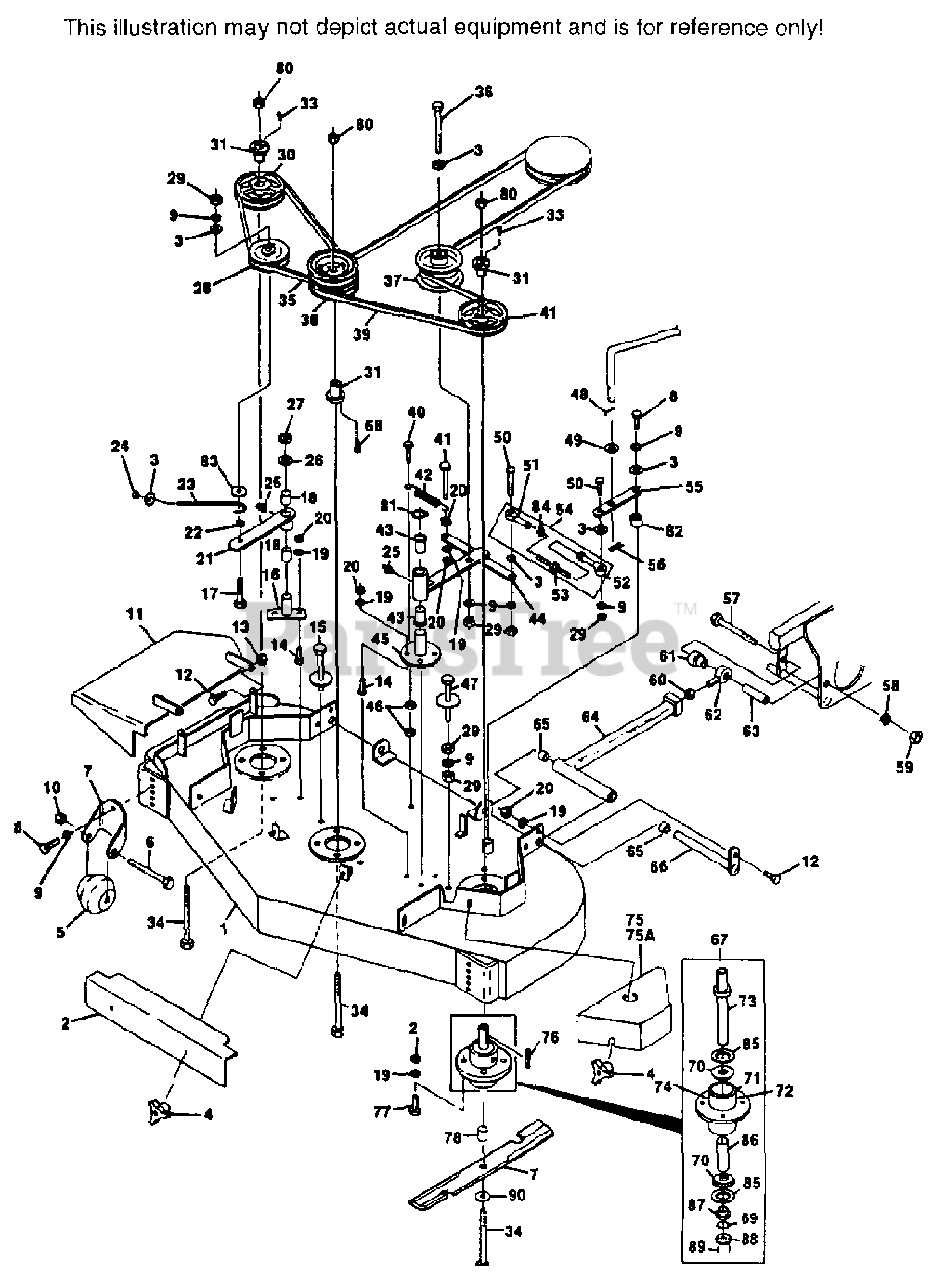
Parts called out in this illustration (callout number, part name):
1	CUTTER DECK(INCLUDES DECALS)
2	BELT COVER - FRONT
4	WING NUT, 3/8-16
5	ANTI-SCALP WHEEL
7	ANTI-SCALP WHEEL BRACKET
10	HEX NUT, 5/8-11 ELASTIC STOP
11	DISCHARGE CHUTE
13	HEX NUT, 5/16-18 ELASTIC STOP
15	BELT GUIDE
18	BUSHING
21	IDLER ARM(INCLUDES BUSHINGS & GREASE FTG.)
22	SPACER
23	"J" ROD
24	HEX NUT, 3/8-16 ELASTIC STOP
25	GREASE FITTING
26	FLAT WASHER, 3/4" SPECIAL
27	RETAINING RING, 3/4" EXTERNAL "E"
28	PULLEY, IDLER
30	PULLEY(INCLUDES ITEMS 31 & 33)
31	TAPERED HUB
34	HEX HEAD BOLT, 5/8-11 X 9-1/2"
35	BELT, RH BLADE DRIVE
37	PULLEY, IDLER - CUTTER ENGAGEMENT
38	PULLEY, DOUBLE(INCLUDES 31)
39	BELT, BLADE DRIVE
41	PULLEY, LH SPINDLE
43	BUSHING
44	IDLER ARM(INCLUDES BUSHINGS & GREASE
45	IDLER PIVOT BASE
47	BELT GUIDE
51	BALL JOINT - RH
52	BALL JOINT - LH
54	TURNBUCKLE ASSEMBLY
55	DECLUTCH LINK, CUTTER ENGAGEMENT
56	HAIR PIN, 1/8" DIA.
60	HEX NUT, 5/8-18 UNF
62	ROD END
63	SPACER
64	PUSH ARM(INCLUDES 25, 60, 62, & 65)
65	BUSHING
66	PUSH ARM SHAFT
67	CUTTER SPINDLE ASSY(COMPLETE, TAPERED)
69	RETAINING RING, 1" EXT INVERTED
70	BEARING & CUP, TAPERED SPINDLE
71	SPINDLE HOUSING, TAPERED SPINDLE
72	GREASE FITTING
73	SPINDLE SHAFT, TAPERED SPINDLE
74	RELIEF FITTING, TAPERED SPINDLE
75	BELT COVER - RH
75A	BELT COVER - LH
76	KEY, 1/4 X 1/4 X 2"
78	SPACER-USE WITH TAPER BEARING SPINDLE
81	RETAINING RING 1-1/8" EXT. E
83	3/8 FLATWASHER, 3/8 X 1-1/2 X .06
84	HEX NUT, 3/8-24 UNF
85	SEAL, CUTTER SPINDLE, TAPERED
86	SPACER, TAPERED SPINDLE
87	BUSHING, TAPERED SPINDLE
88	1/4" BLADE SPACER, TAPERED SPINDLE
90	FLAT WASHER 5/8 X .688 X .1.75 X .134
